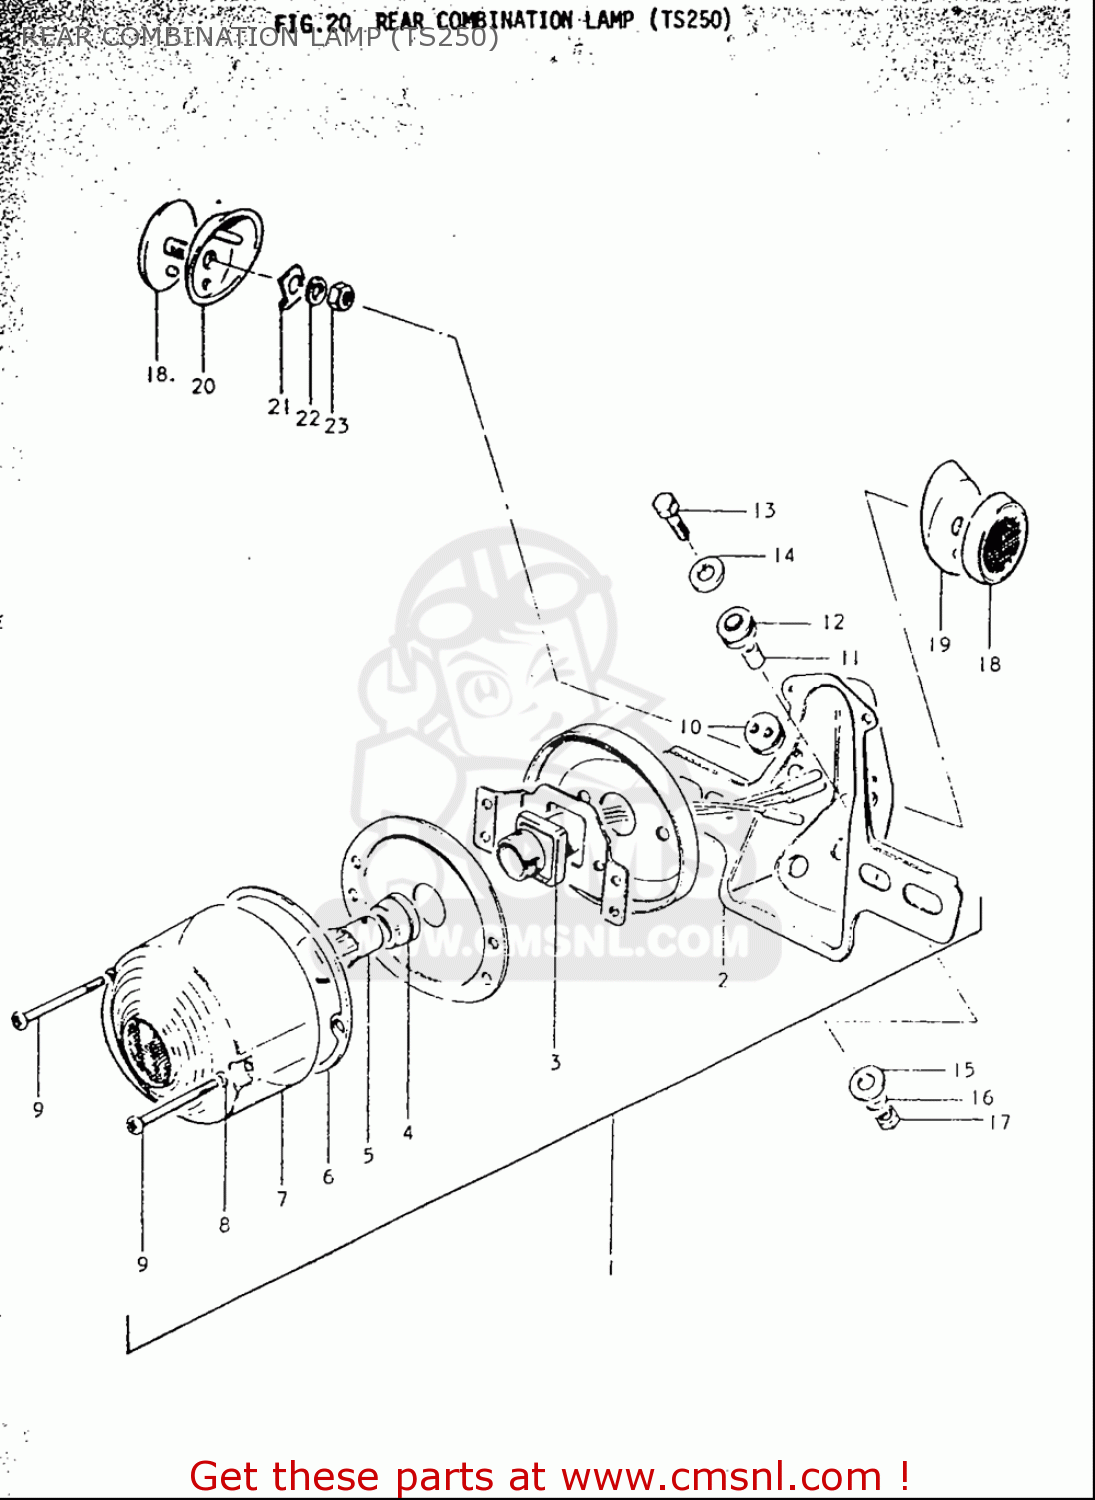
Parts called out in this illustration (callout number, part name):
5	BULB(6V17/5.3W,STANLEY,A4813)
7	LENS,RR COMBINATION LAMP
10	GROMMET,REAR COMBINATION LAMP
11	SPACER
12	CUSHION
13	BOLT
14	WASHER(6.5X20X1.6)
15	WASHER
16	WASHER,LOCK
17	NUT
22	WASHER,LOCK
23	NUT
